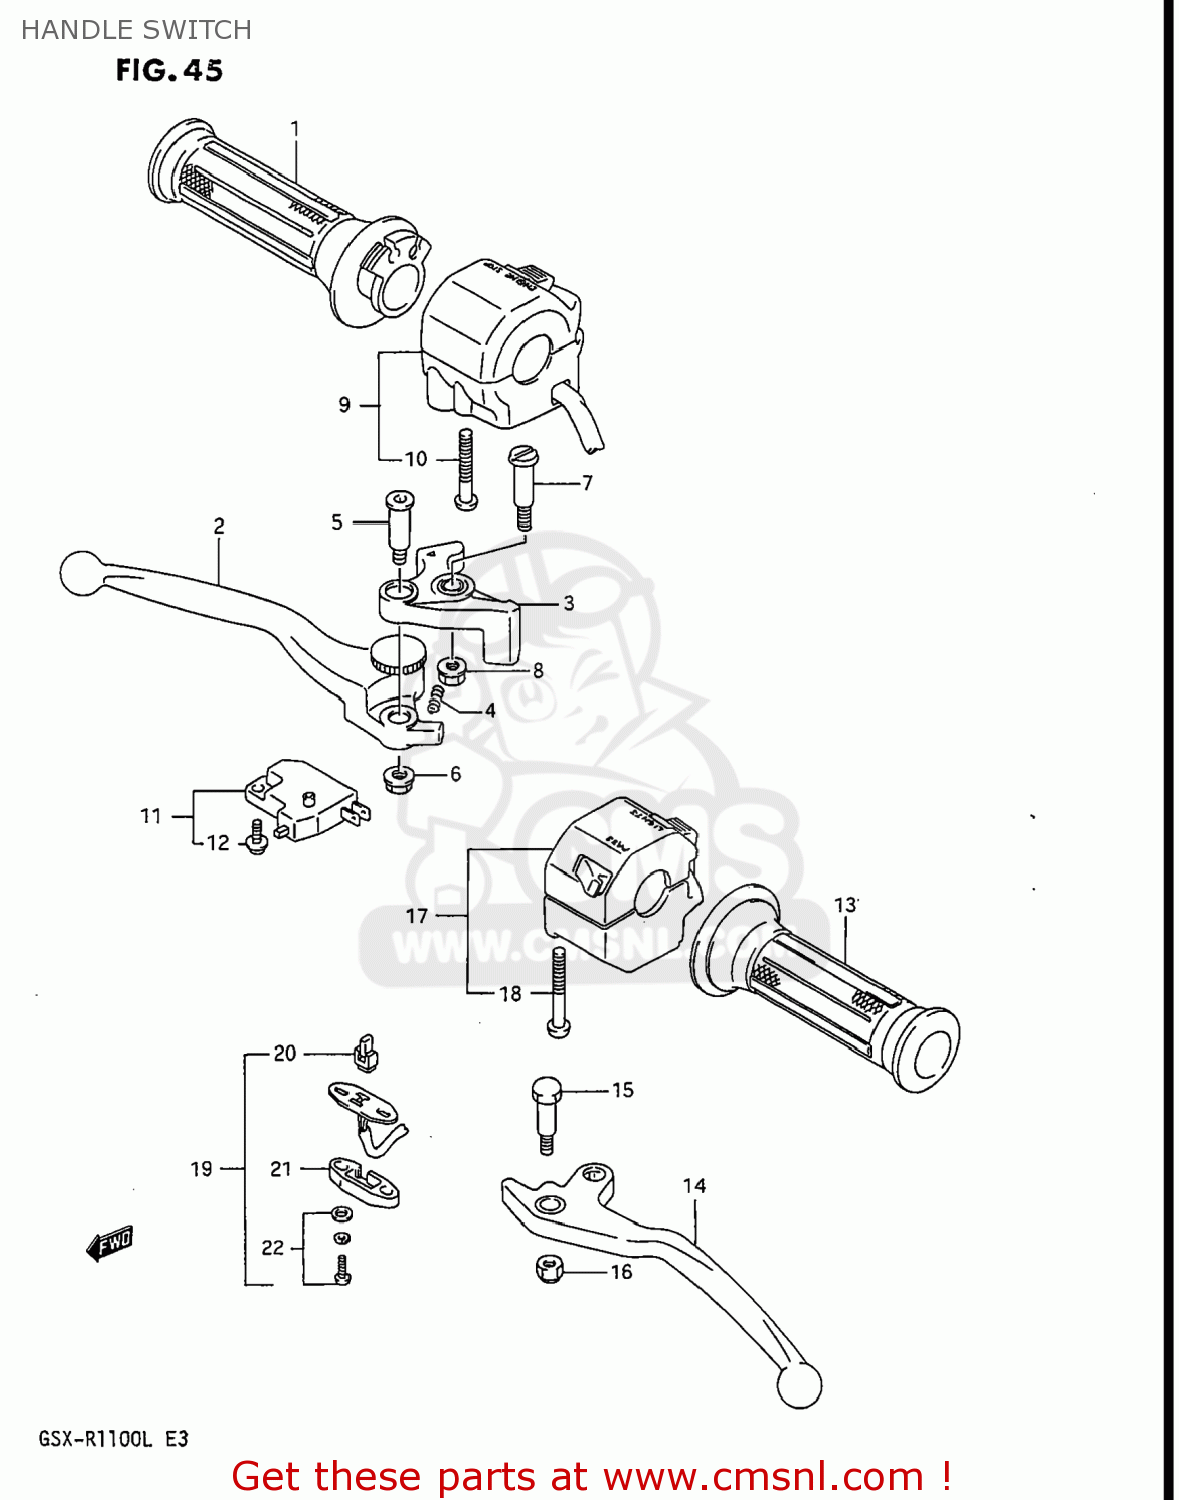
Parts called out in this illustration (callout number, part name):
1	GRIP,THROTTLE
2	LEVER,ADJUST
3	KNOCKER
4	SPRING
5	BOLT,LEVER
6	NUT
7	BOLT,LEVER PIVOT
8	NUT 6MM
9	SWITCH ASSEMBLY,HANDLE,RIGHT
10	SCREW, 5X45
11	SWITCH ASSEMBLY,STOP
12	SCREW
13	GRIP,L
14	LEVER,CLUTCH (SILVER)
15	BOLT,LEVER
16	NUT
17	SWITCH ASSEMBLY,HANDLE,LEFT
18	SCREW, 5X45
19	SWITCH ASSEMBLY,CLUTCH
20	CONTACT,SWITCH
21	COVER,FR BK TERMINAL BASE
22	SCREW
